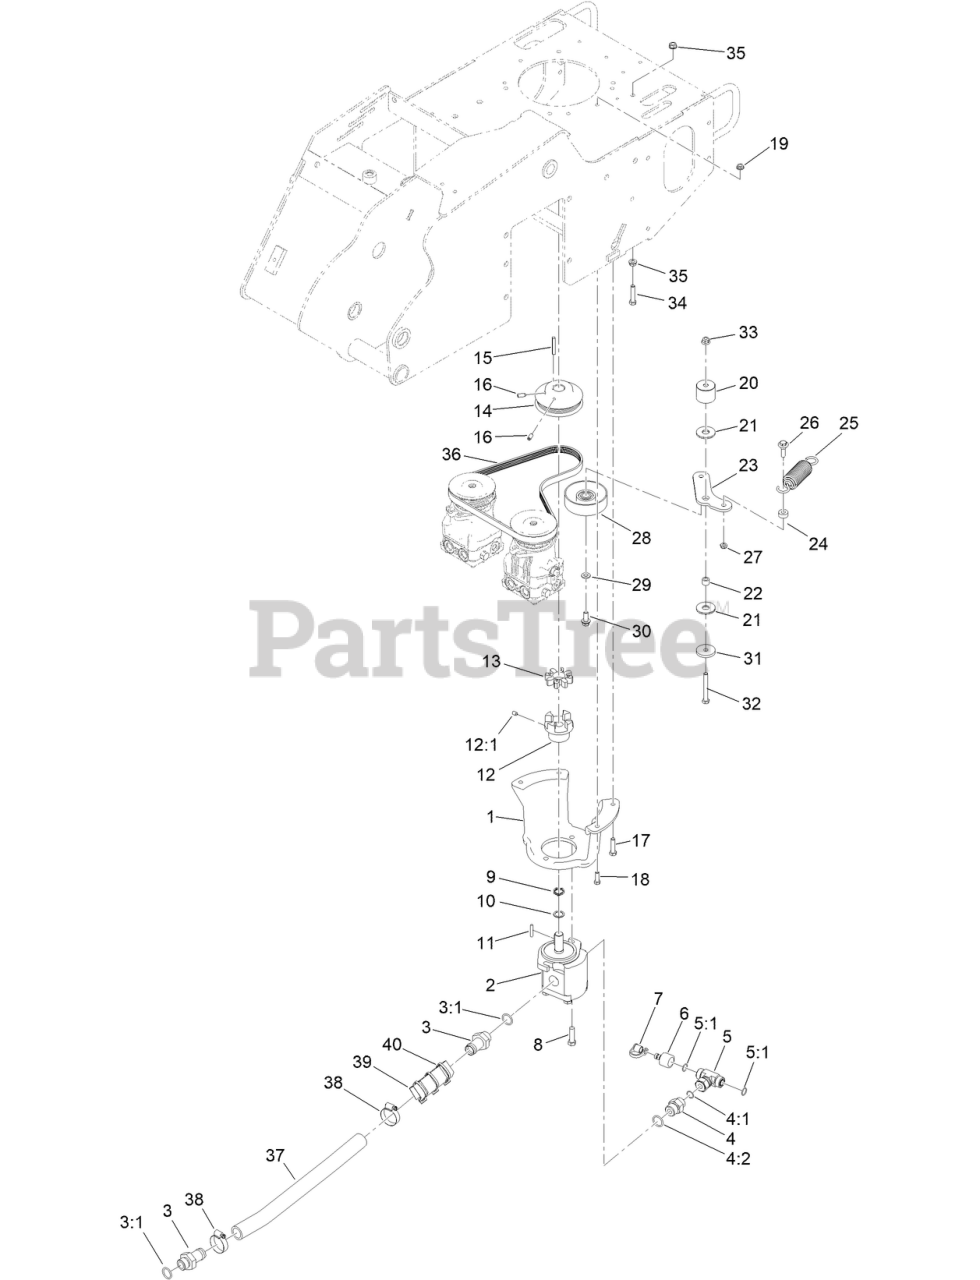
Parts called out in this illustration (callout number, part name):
1	MOUNT-PUMP
2	GEAR PUMP ASM
3	FITTING
3:1	O-RING
4	FITTING-STRAIGHT
4:1	O-RING
4:2	O-RING
5	FITTING-HYD, TEE
5:1	O-RING
6	NIPPLE
7	CAP-DUST
8	SCREW-HH
9	WASHER-WAVE
10	WASHER-THRUST
11	KEY-SQUARE
12	COUPLER-FLEX
12:1	SCREW-SET, HSH
13	COUPLER-SPIDER
14	PULLEY-ENGINE
15	KEY-SQUARE
16	SCREW-SET, HSH
17	SCREW-HH
18	SCREW-HH
19	NUT-HF
20	SPACER-IDLER
21	WASHER-FRICTION, COMPOSITE
22	BUSHING-LEVER, LIFT
23	ARM-IDLER
24	SPACER
25	SPRING-EXTENSION
26	SCREW-SHOULDER, HWH
28	PULLEY-IDLER
29	WASHER-FLAT
30	SCREW-HHF
31	WASHER-PLAIN
32	SCREW-HH
33	NUT-HF, NI
34	SCREW-HH
35	NUT-HHF, WHIZ
36	BELT-V
37	HOSE-SUCTION
39	PROTECTOR-HOSE
40	TIE-CABLE
